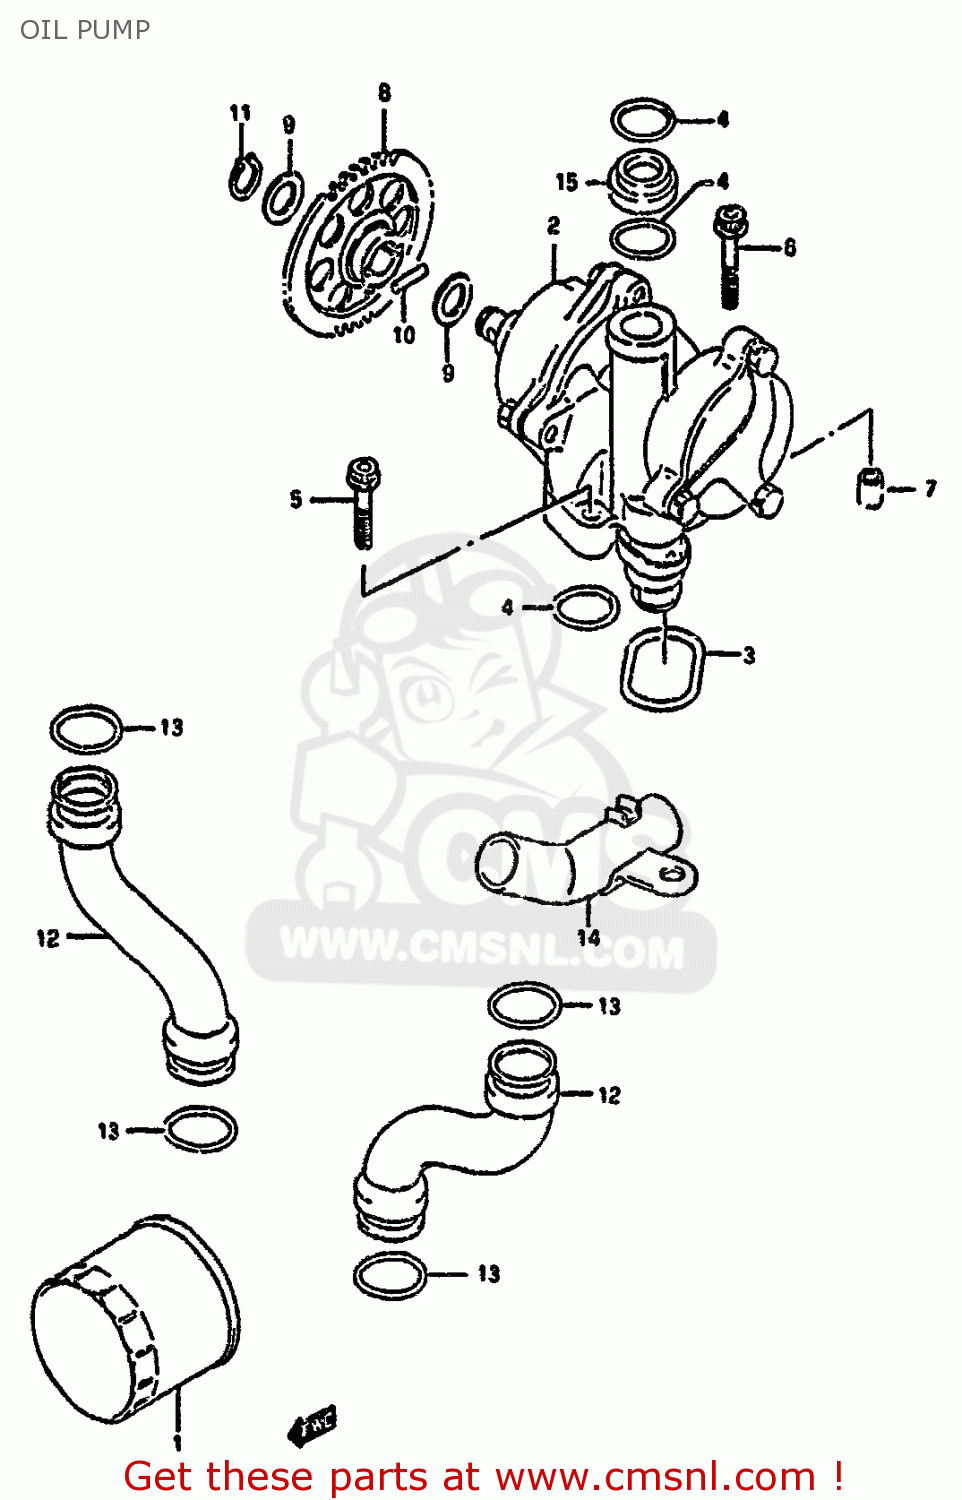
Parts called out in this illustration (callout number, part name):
1	FILTER ASSEMBLY,ENGINE OIL
2	PUMP ASSEMBLY,OIL
3	O RING,OIL PUMP
4	O RING(D:3.2,ID:17.8)
5	BOLT
6	BOLT
7	PIN
8	GEAR,OIL PUMP DRIVEN
9	SHIM
10	PIN(5X18)
11	CIRCLIP,12 MM
12	PIPE,OIL OUTLET
13	O RING(D:3.7,ID:21.7)
14	PIPE COMP,OIL OUTLET
15	SPACER,OIL PUMP
